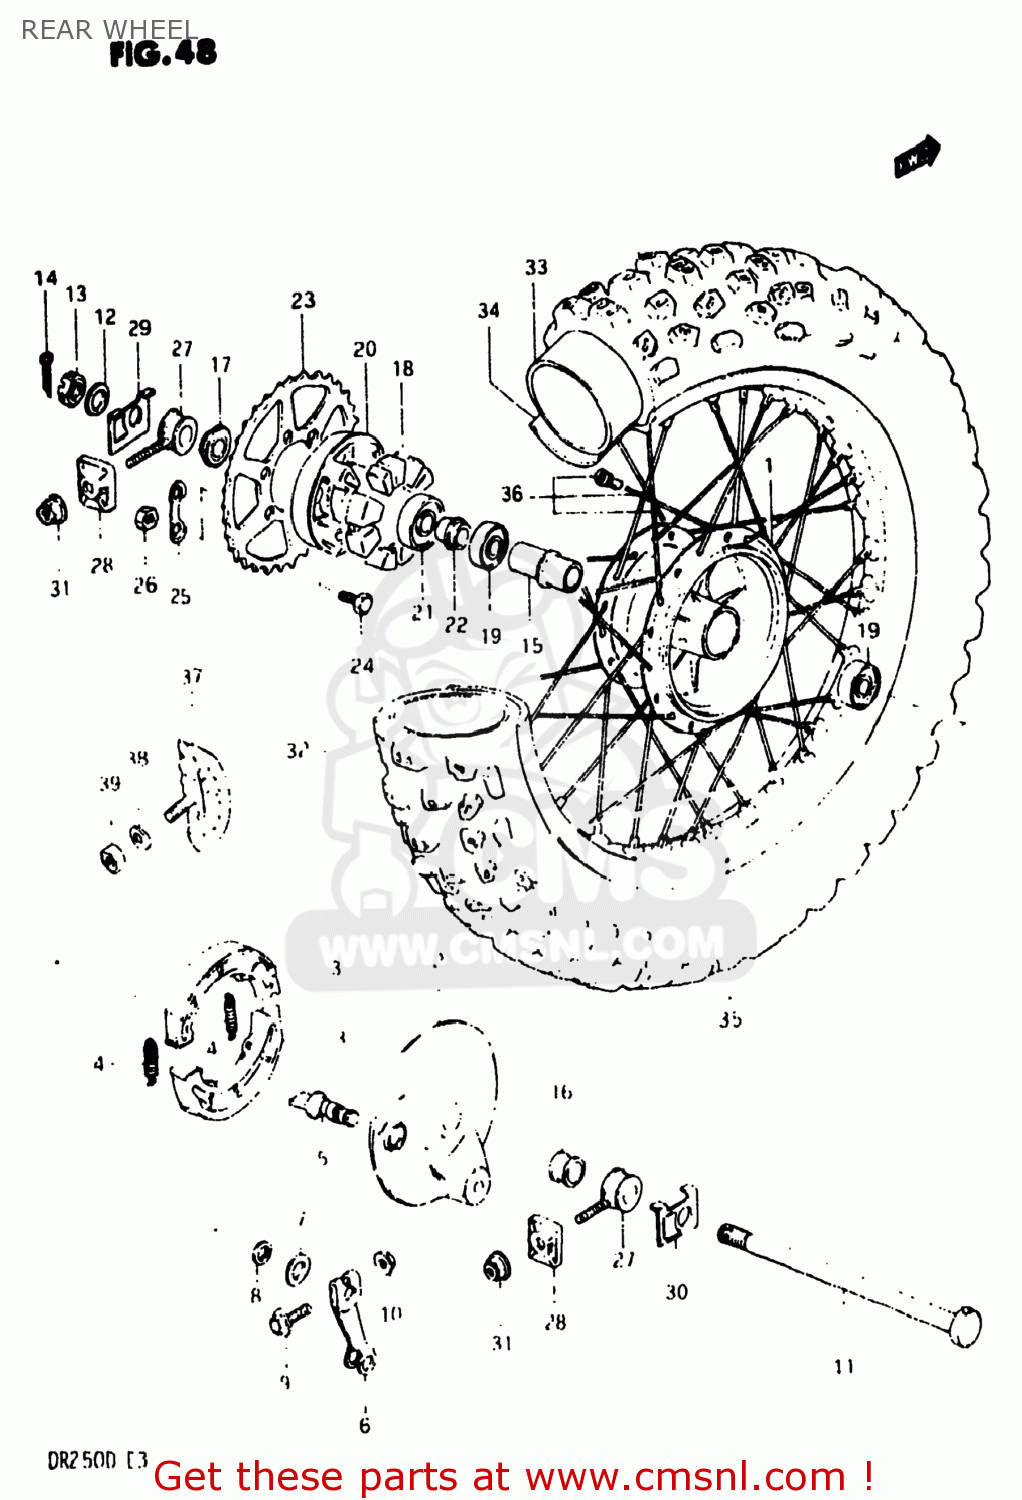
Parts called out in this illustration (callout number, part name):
1	DRUM,REAR HUB
2	PANEL,REAR HUB
3	SHOE,BRAKE
4	SPRING(L:34)
5	CAM,FRONT BRAKE
6	CAM,LEVER
7	WASHER (14.5X22X1.6)
8	O-RING (D:2.4 ID:13.8)
9	BOLT 6X35
10	NUT
11	AXLE,REAR
12	WASHER
13	NUT
14	PIN,COTTER
15	SPACER,REAR HUB BEARING
16	SPACER,REAR AXLE,RIGHT
17	SPACER,REAR AXLE
18	CUSHION,REAR DRUM
19	BEARING
20	DRUM,REAR SPROCKET MOUNT
21	BEARING
22	SPACER,REAR HUB BEARING
23	SPROCKET,RR
24	BOLT
25	WASHER
26	NUT
27	ADJUSTER,CHAIN
28	PLATE,CHAIN ADJUSTER GUIDE,R
29	WASHER,CHAIN ADJUST GUIDE
30	WASHER,CHAIN ADJUST GUIDE
31	NUT
32	TIRE
33	TUBE ASSEMBLY,WHEEL,INNER
34	PROTECTOR,WHEEL,INNER
35	RIM,REAR WHEEL
36	SPOKE ASSY,RR WHEEL
37	STOPPER,BEAD
38	WASHER
39	NUT
